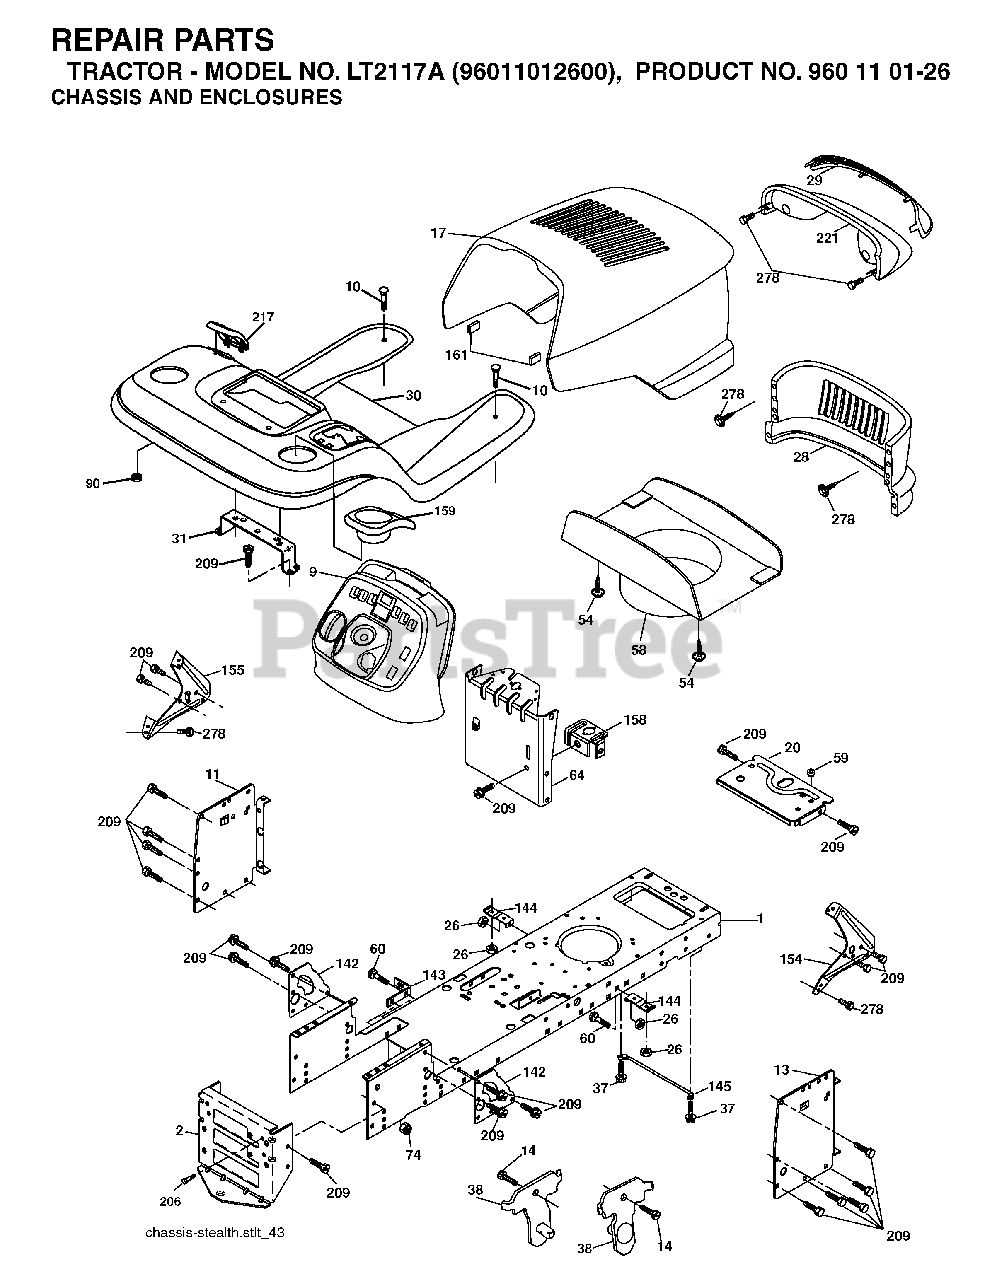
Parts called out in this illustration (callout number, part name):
1	CHASSIS STAMPING
2	DRAWBAR, 12GA
10	BOLT D
13	PANEL DASH RH
26	NUT
38	BRACKET.ASM.PIVOT.MOWER.REAR
54	SCREW.WSHD.HEX10-32X5/8
58	DUCT HOOD
64	DASH LOWER
74	LOCKNUT
142	PLATE REINFORCEMENT
143	BRACKET, SWAYBAR CHASSIS
144	BRKT, FOOT REST
145	ROD PIVOT CHASSIS/HOOD
161	EXTRUSION BUMPER
206	SHOULDER BOLT 5/16-18TT
209	SCREW, 3/8-16X3/4
278	SCREW
